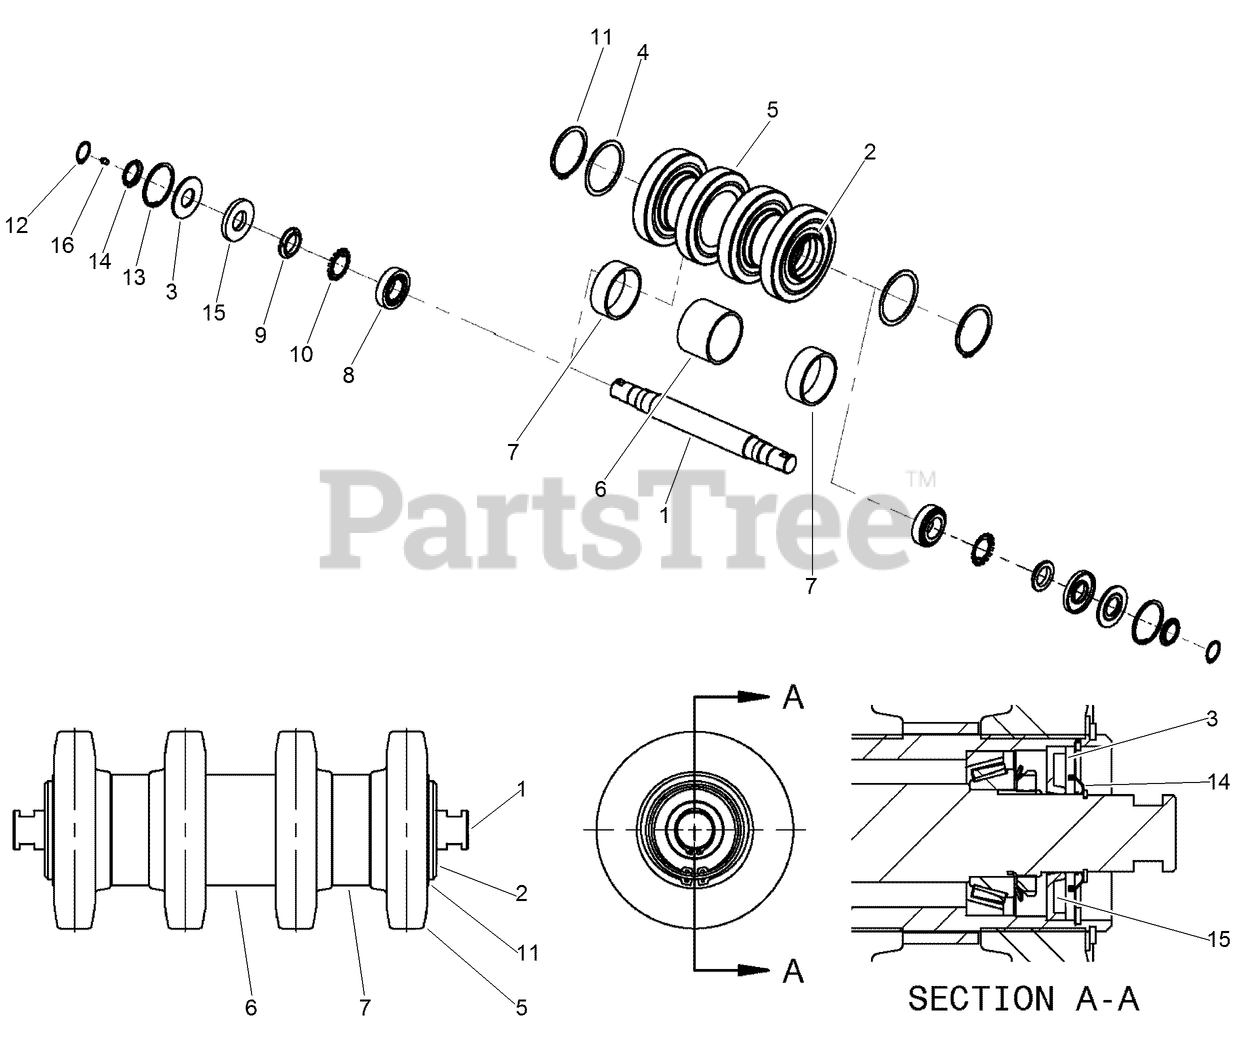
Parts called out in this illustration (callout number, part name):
1	AXLE - Track Roller
2	TUBING - Axle
3	SEAL - Double Lip
4	RING-RETAING, TRACK WHEEL
5	WHEEL-MOLDED, TRACKS, 8IN
6	Spacer
7	Spacer
8	BEARING - Track Axle
9	NUT-GROOVED, M45
10	WASHER-LOCK, TABBED, M45
11	RING-RETAINING,EXTERNAL 4IN
12	RING-EX, RT
13	RING - Retaining, Internal
14	SEAL-OIL, DOUBLE LIP, 58MM OD
15	SEAL - Oil, 40 mm ID x 90 mm OD x 10 mm
16	FITTING-Lube 1/8-27 Dryseal PTF
